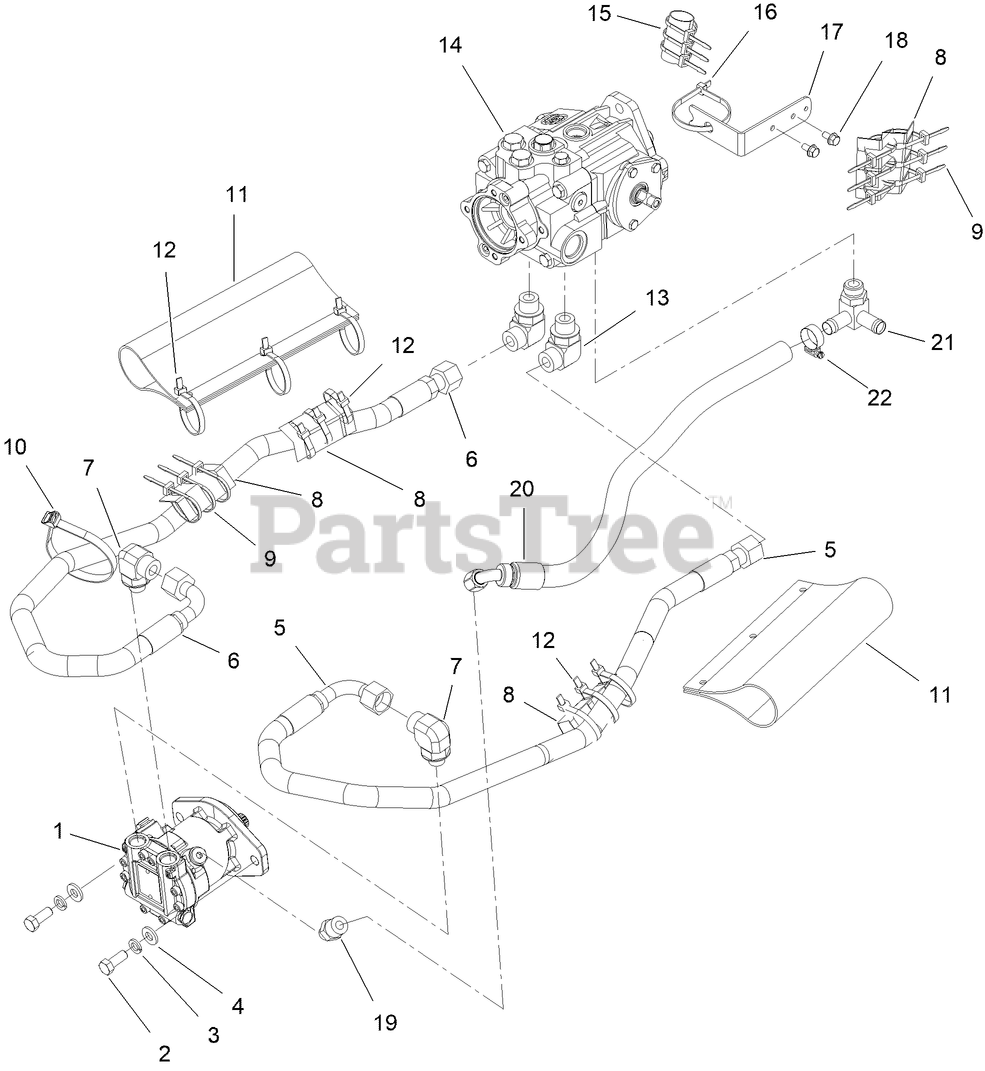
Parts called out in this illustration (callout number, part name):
1	HYDRAULIC MOTOR (MP1 24CC)
2	SCREW-HH
3	WASHER-LOCK
5	HOSE (12OFX90M-50"-3000)
6	HOSE (12OFX90M-50"-3000)
7	CONNECTOR (10S-12O90)
8	PROTECTOR-HOSE
9	TIE-CABLE
10	CABLE TIE (1/2") 20" LG
11	BOOT-HOSE
12	TIE-CABLE
13	CONNECTOR (12S-12O90)
14	HYD VARIABLE PUMP ASM
15	PROTECTOR-HOSE
16	TIE-CABLE
17	BRACKET-HOSE
18	SCREW-HHF
19	CONNECTOR (08S-10O)
20	HOSE (10FFORX, -12HOSE - 29"-E-Z-FORM)
22	CLAMP-HOSE
